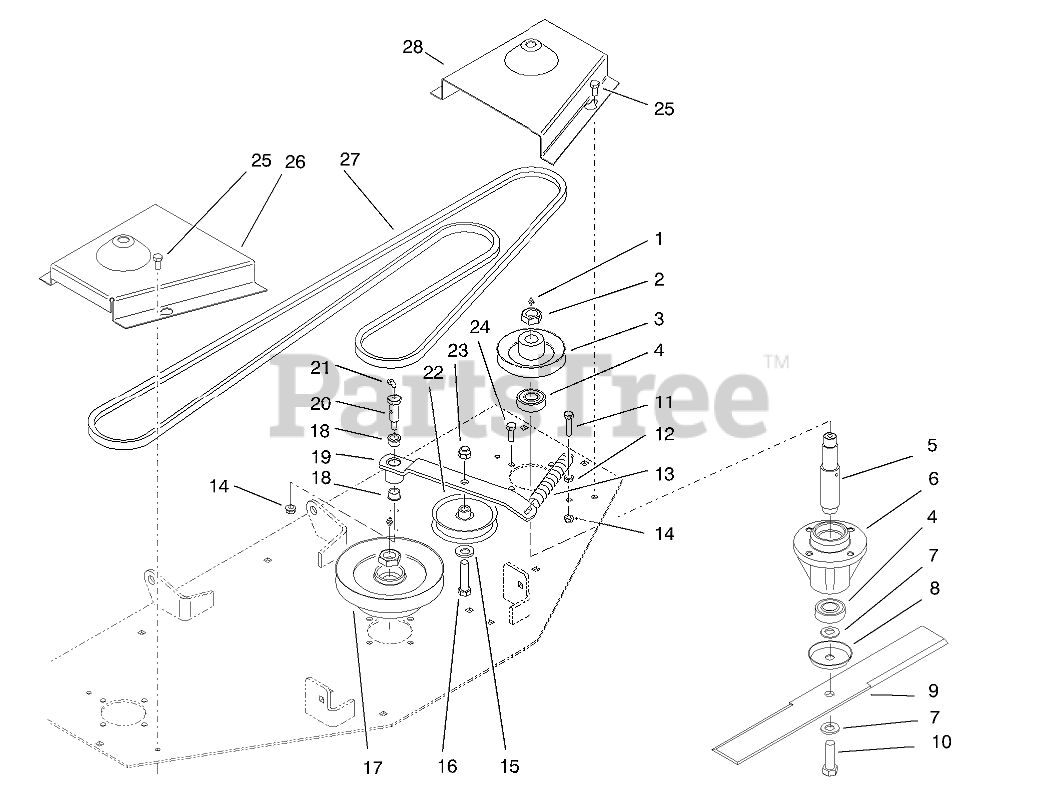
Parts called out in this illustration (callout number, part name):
1	FITTING-GREASE
2	NUT-LOCK, NI
3	PULLEY
4	BEARING-BALL
5	SHAFT - SPINDLE
6	HOUSING - SPINDLE
7	WASHER-SPECIAL
8	CUP-SPINDLE
9	BLADE
10	SCREW-HH
11	SCREW-HH
12	NUT-JAM
13	SPRING-EXTENSION
14	NUT-LOCK, NI
15	WASHER-FLAT
16	SCREW-HH
17	PULLEY - DOUBLE 60"
18	BUSHING
19	IDLER ARM
20	BOLT-SHOULDER
21	FITTING-GREASE, 90 DEG
22	PULLEY-IDLER
23	NUT-LOCK, NI
24	SCREW-HH, LOCK
25	SCREW-HWH, TAPTITE
26	COVER-BELT, RH,
27	BELT - V DECK
28	COVER-BELT,LH,
